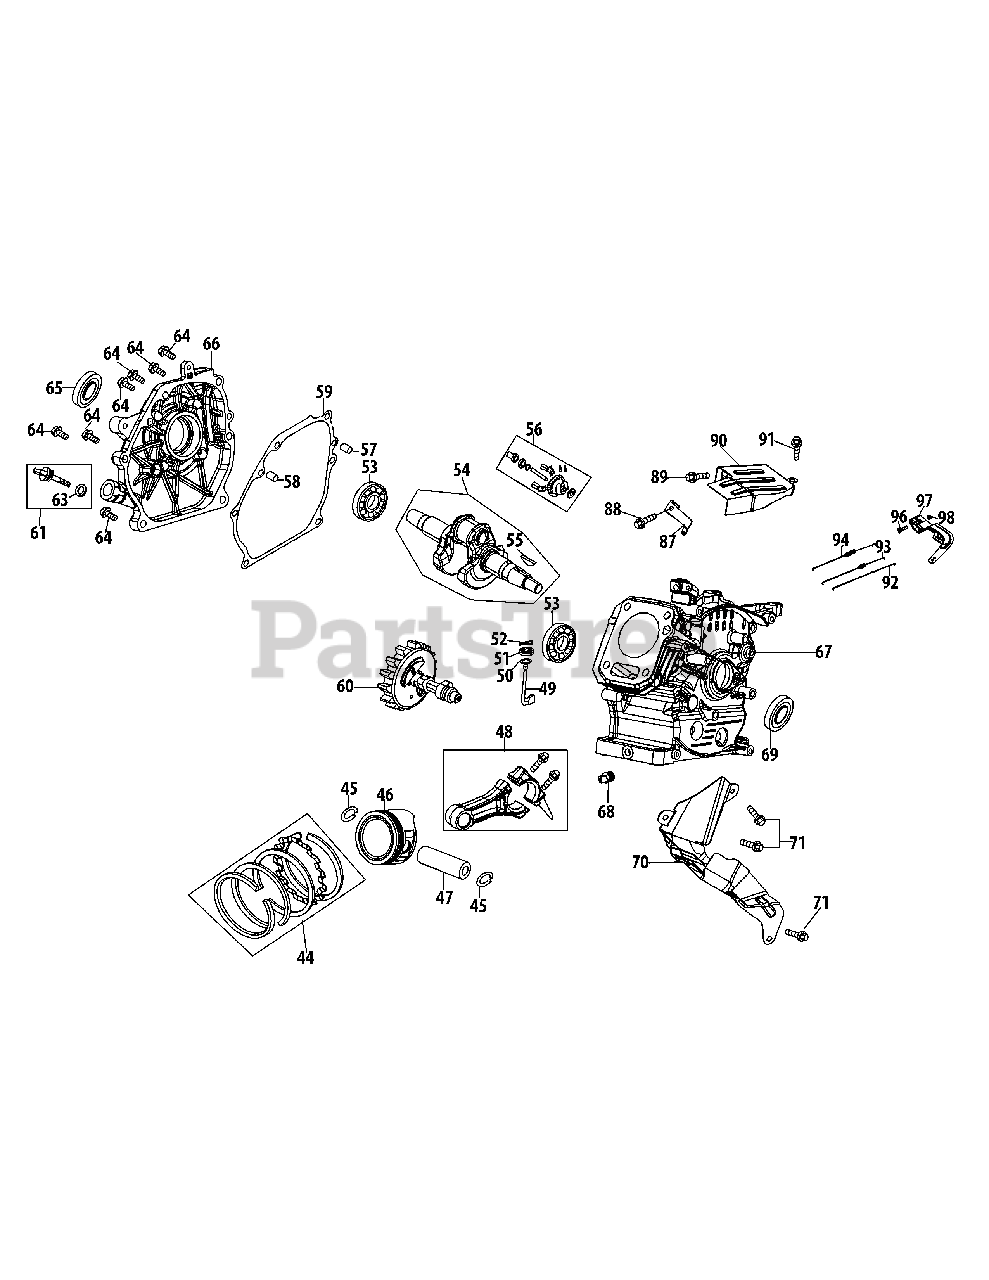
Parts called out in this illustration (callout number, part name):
44	Piston Ring Set
45	Clip, Piston Pin, 18Mm
46	Piston
47	Pin, Piston
48	Connecting Rod Assembly
49	Goverror Arm
50	O-Ring
51	Governor Seal
52	Pin, Lock
53	Bearing, 6205
54	Crankshaft Kit
55	Woodruff Key
56	Governor Gear/Shaft Assy
57	Pin, Dowel, 9×14
58	Pin, Dowel, 7×14
59	Gasket, Crankcase Cover
60	Camshaft Assy
61	Dipstick Assembly
63	O-Ring
64	Bolt, Flange, M6×28
65	Oil Seal, 25×41.25×6
66	Crankcase Cover Kit
67	Crankcase Kit
68	1/8 Npt Oil Drain Plug
69	Oil Seal
70	Baffle, Cylinder
71	Bolt, Flange, 6×10
87	Covernor Spring Bracket
88	Boltm6×14
89	Bolt, Flange, 8×14
90	Governor Shield
91	Bolt, Flange, M6×28
92	Rod, Governor
93	Throttle Return Spring
94	Spring, Governor
96	Bolt, Governor Arm
97	Arm, Governor
98	Nut, Flange, 6mm
